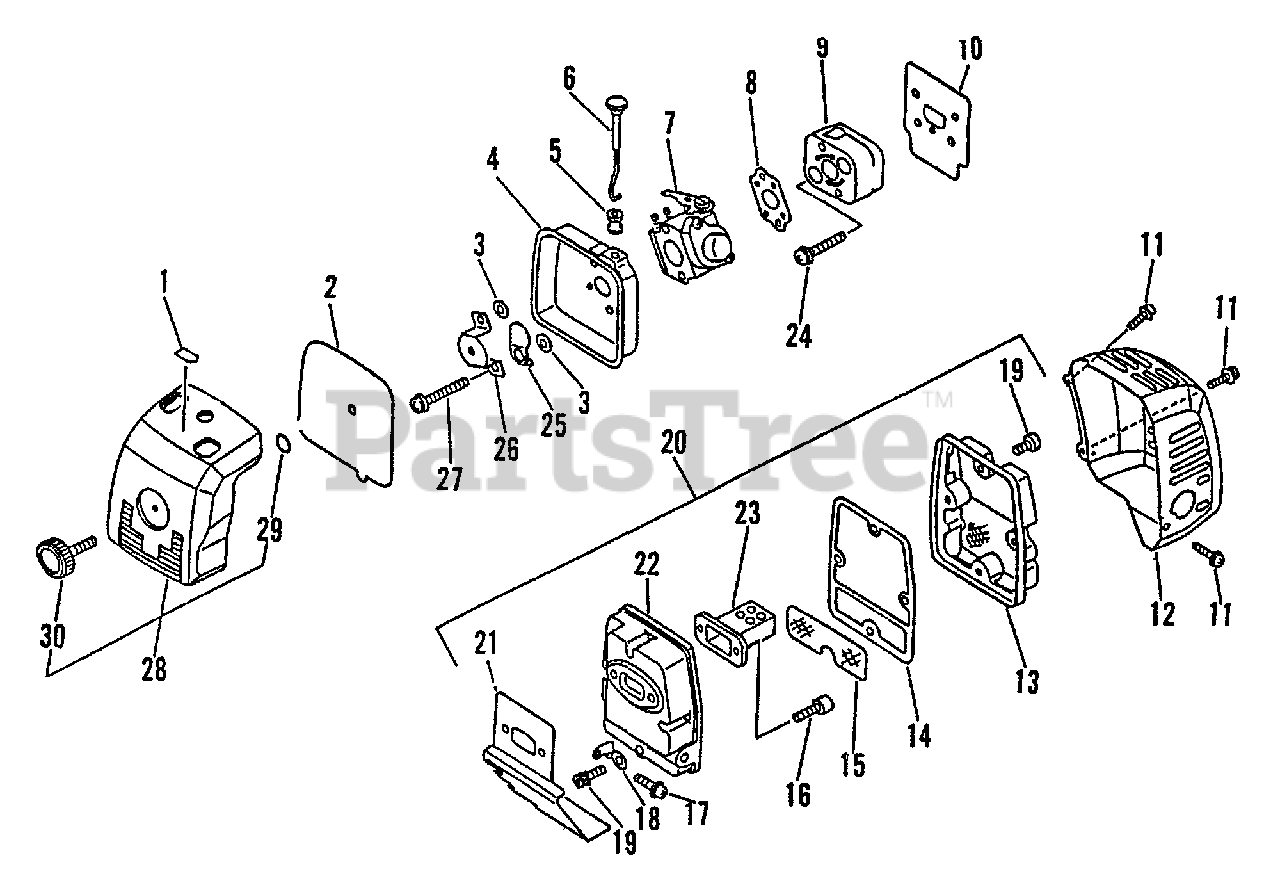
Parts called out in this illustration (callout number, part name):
1	LABEL, CHOKE
2	FILTER, HEAVY-DUTY AIR
3	WASHER 5.2×8×0.8T
4	CASE, AIR FILTER
5	GROMMET, CHOKE
6	ROD, CHOKE
7	CARBURETOR - C1U-K20B
8	GASKET, INTAKE
9	INSULATOR
10	GASKET
11	SCREW 4×8
12	COVER, MUFFLER
13	COVER, MUFFLER
14	GASKET, EXHAUST
15	SCREEN, SPARK ARRESTER
16	BOLT M5×18
17	SCREW 5×10
18	BRACKET, MUFFLER
19	BOLT 5×14
20	MUFFLER ASSY
21	GASKET, MUFFLER
23	SILENCER
24	SCREW 5×25
25	SHUTTER, CHOKE
26	PLATE, PREVENT
27	SCREW 5×50
28	AIR FILTER COVER ASSY
29	O-RING 3
30	THUMBSCREW
